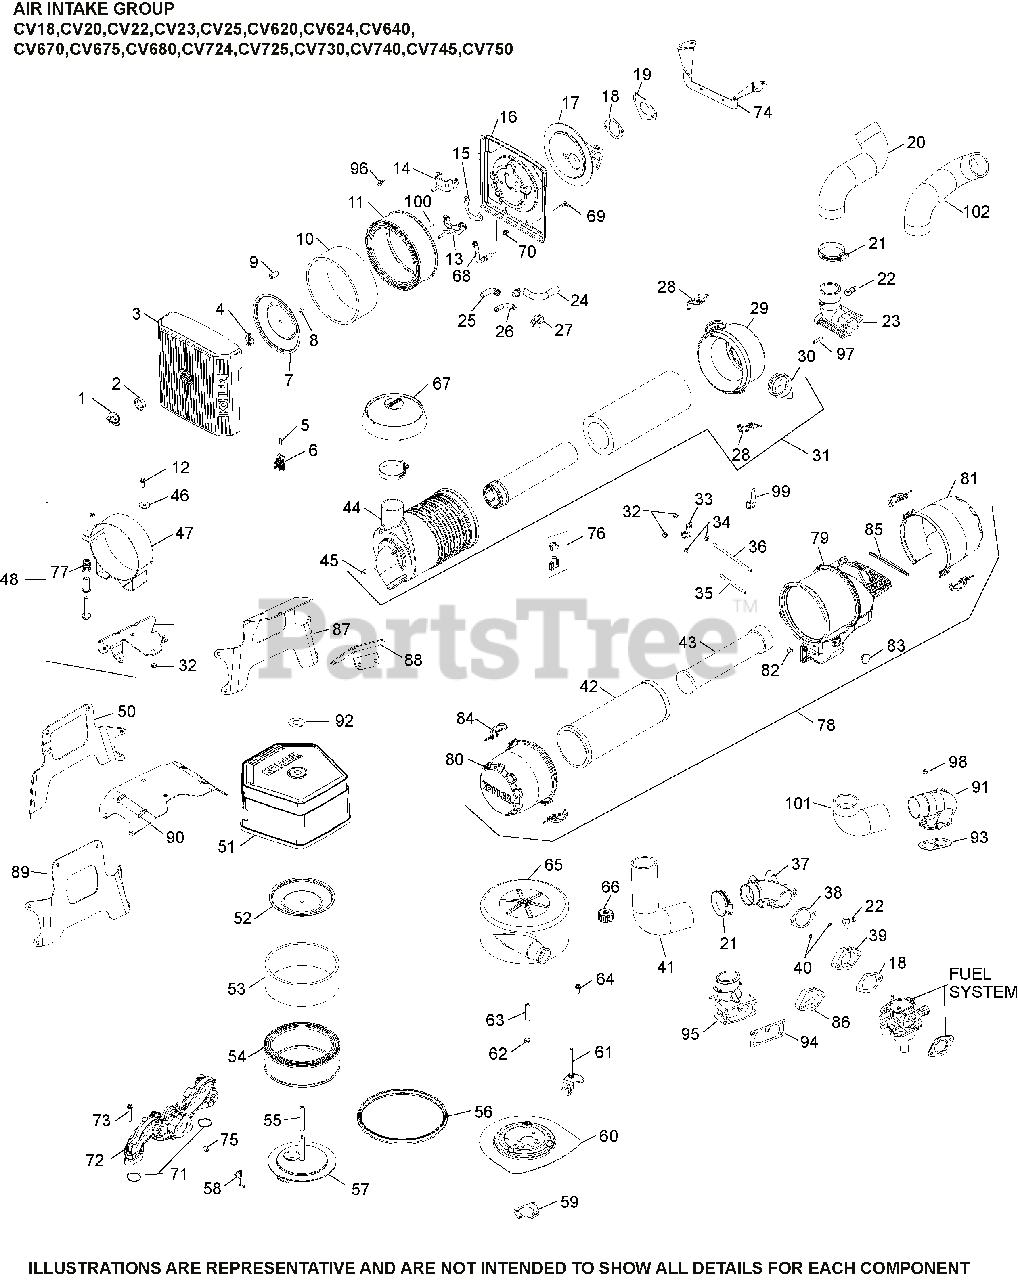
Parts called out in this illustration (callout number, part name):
12	SCREW, FLG M6X1.0X16
12	SCREW, THREAD FORMING
18	GASKET, AIR CLEANER BASE
19	GASKET, CARBURETOR
20	HOSE, AIR CLEANER
21	CLAMP, HOSE-USE 25 237 21-S
22	CONNECTOR, HOSE
23	KIT, ELBOW
28	CLIP - USE 62 154 07-S
29	COVER ASSEMBLY, AIR CLEANER
30	VALVE, DUST EJECTOR
31	AIR CLNR, CANISTER-USE 25 048 17-S
32	NUT, LOCK M6X1.0
33	CLIP, CABLE
34	WASHER
35	STUD, M6X1.0X180
36	STUD, M6X1.0X140
37	ADAPTER, ELBOW
38	GASKET, AIR CLEANER ADAPTER
40	O-RING
42	ELEMENT, AIR FILTER - PRIMARY
43	ELEMENT, AIR FILTER - SAFETY
44	HOUSING, HD AIR CLEANER
45	PLUG, PIPE
46	WASHER, FLAT 1/4" (O.D. 1")
47	BRACKET, AIR CLEANER-USE 24 126 191-S
48	BRACKET, AIR CLEANER -USE 24 126 186-S
49	BRACKET, AIR CLEANER-USE 24 126 184-S
50	BRACKET, MAIN SUPPORT-USE 24 126 185-S
67	HOOD, AIR CLEANER (5.25)-USE 25 324 04-S
77	SPRING, AIR CLEANER BRACKET
86	ADAPTER, BREATHER FITTING
97	CAP, MASKING
